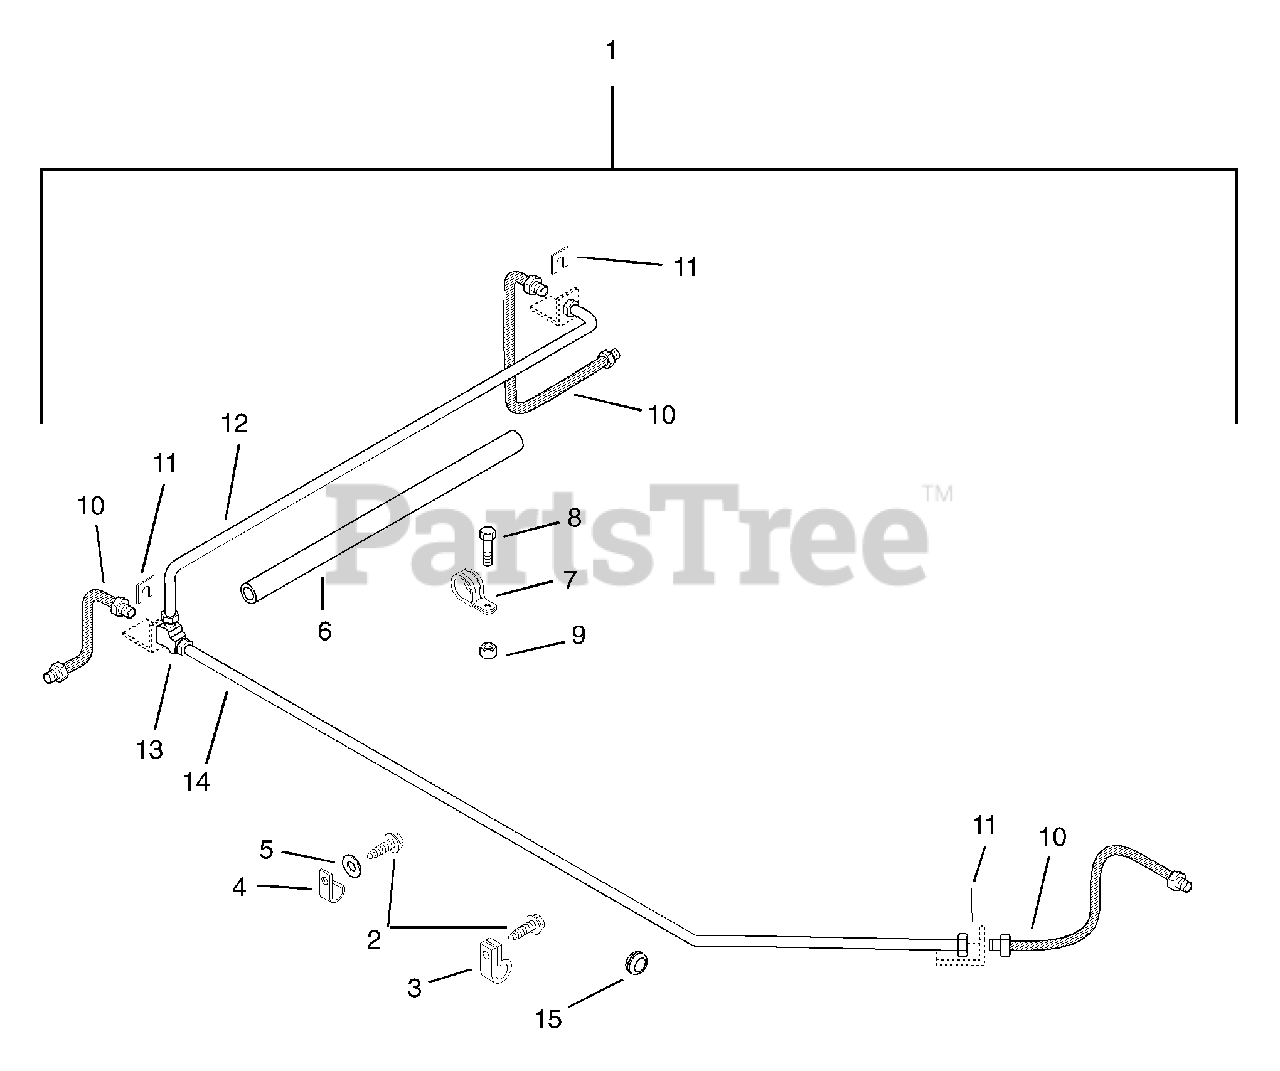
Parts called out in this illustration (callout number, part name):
1	Brake Line Kit
2	Screw-Tapping-Hex Washer Head .25 x .50
5	Washer-Flat-Steel .38 x .875 x .083
6	Tube-Brake Line Protective
7	Clamp-Steel 1.0
8	Bolt-Hex .38-16 x 1.00 Grade 5
9	Nut-Locking-Center .38-16
10	Hose-18" Hydraulic Brake
11	Clip-Hose
12	Line-Brake 3/16 x 72
13	Tee-3/16 Adapter
14	Line-Brake 3/16 x 100
